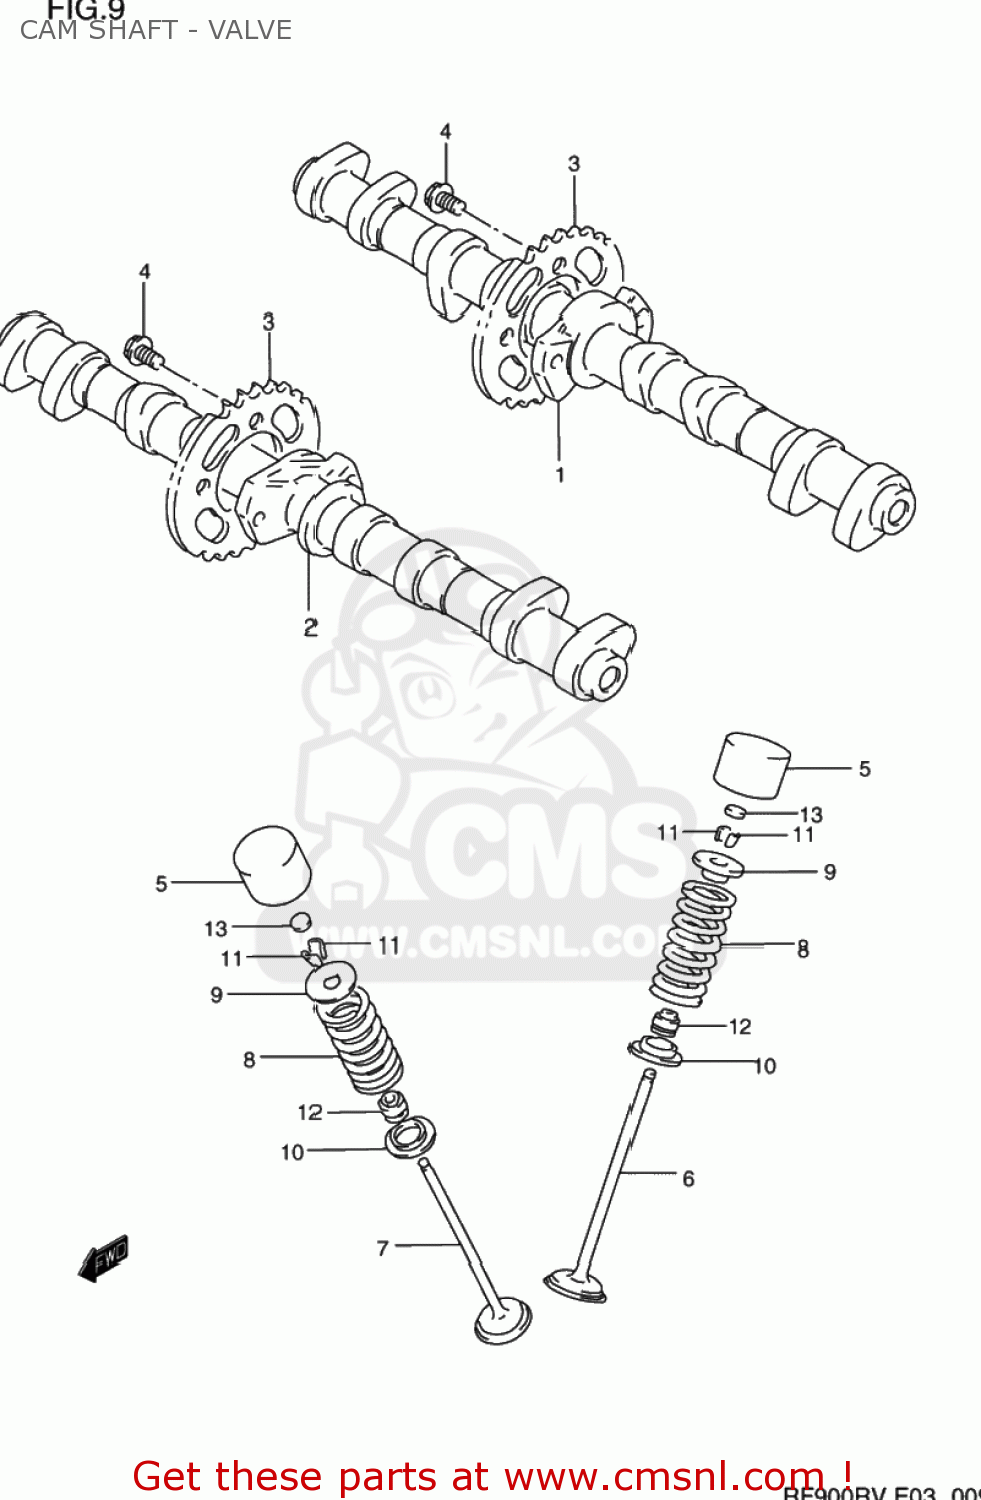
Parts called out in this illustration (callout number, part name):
1	CAMSHAFT,INTAKE
2	CAMSHAFT,EXHAUST
3	SPROCKET,CAMSHAFT
4	BOLT(7X11)
5	TAPPET
6	VALVE,INTAKE
7	VALVE,EXHAUST
8	SPRING,VALVE
9	RETAINER,VALVE SPRING
10	SEAT,VALVE SPRING
11	COTTER VALVE
12	SEAL,OIL(4.5X10X8)
13	SHIM,TAPPET
14	SHIM SET,TAPPET
15	CASE,TAPPET SHIM
